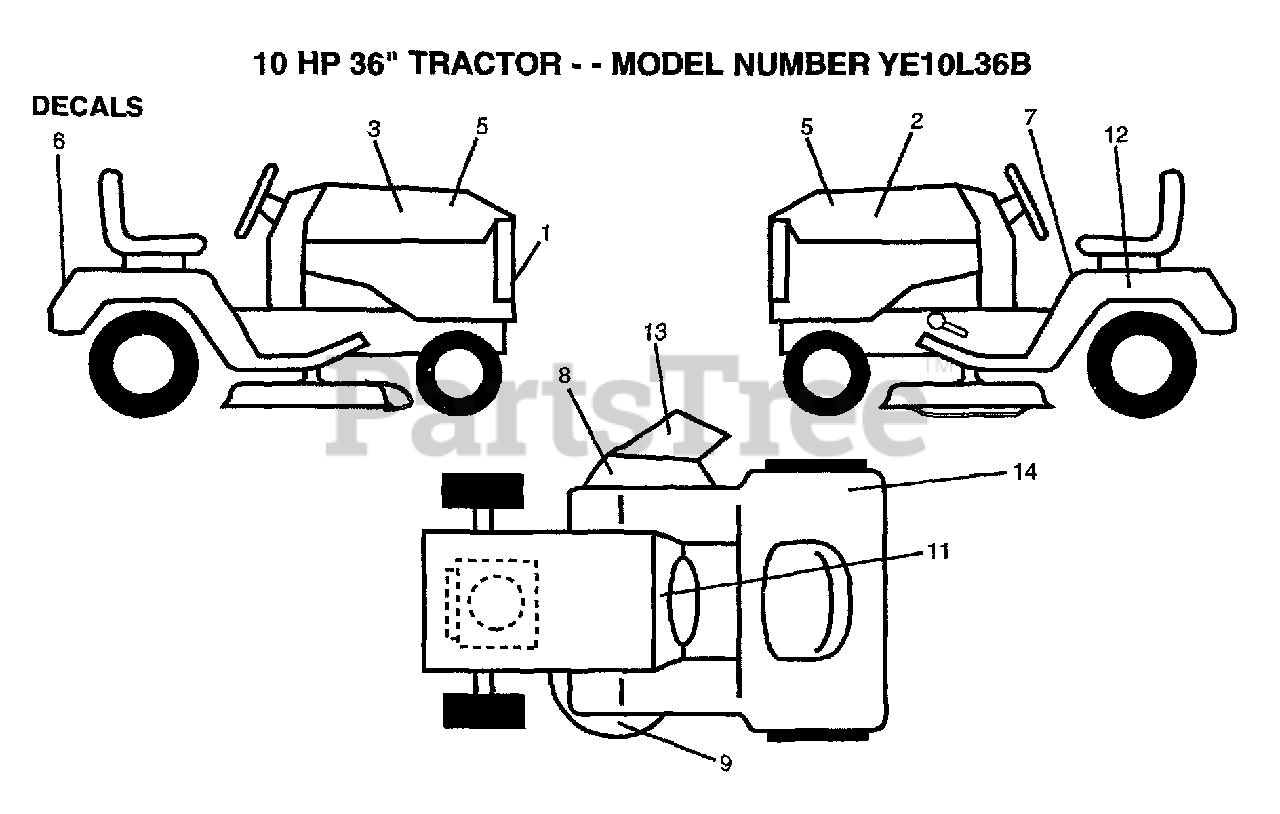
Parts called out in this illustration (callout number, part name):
1	"DECAL,LIGHT BOX"
5	DECAL MODEL SIDE PANEL
7	DECAL CAUTION
8	DECAL WARNING
9	DECAL YT
12	DECAL
13	DECAL WARNING
